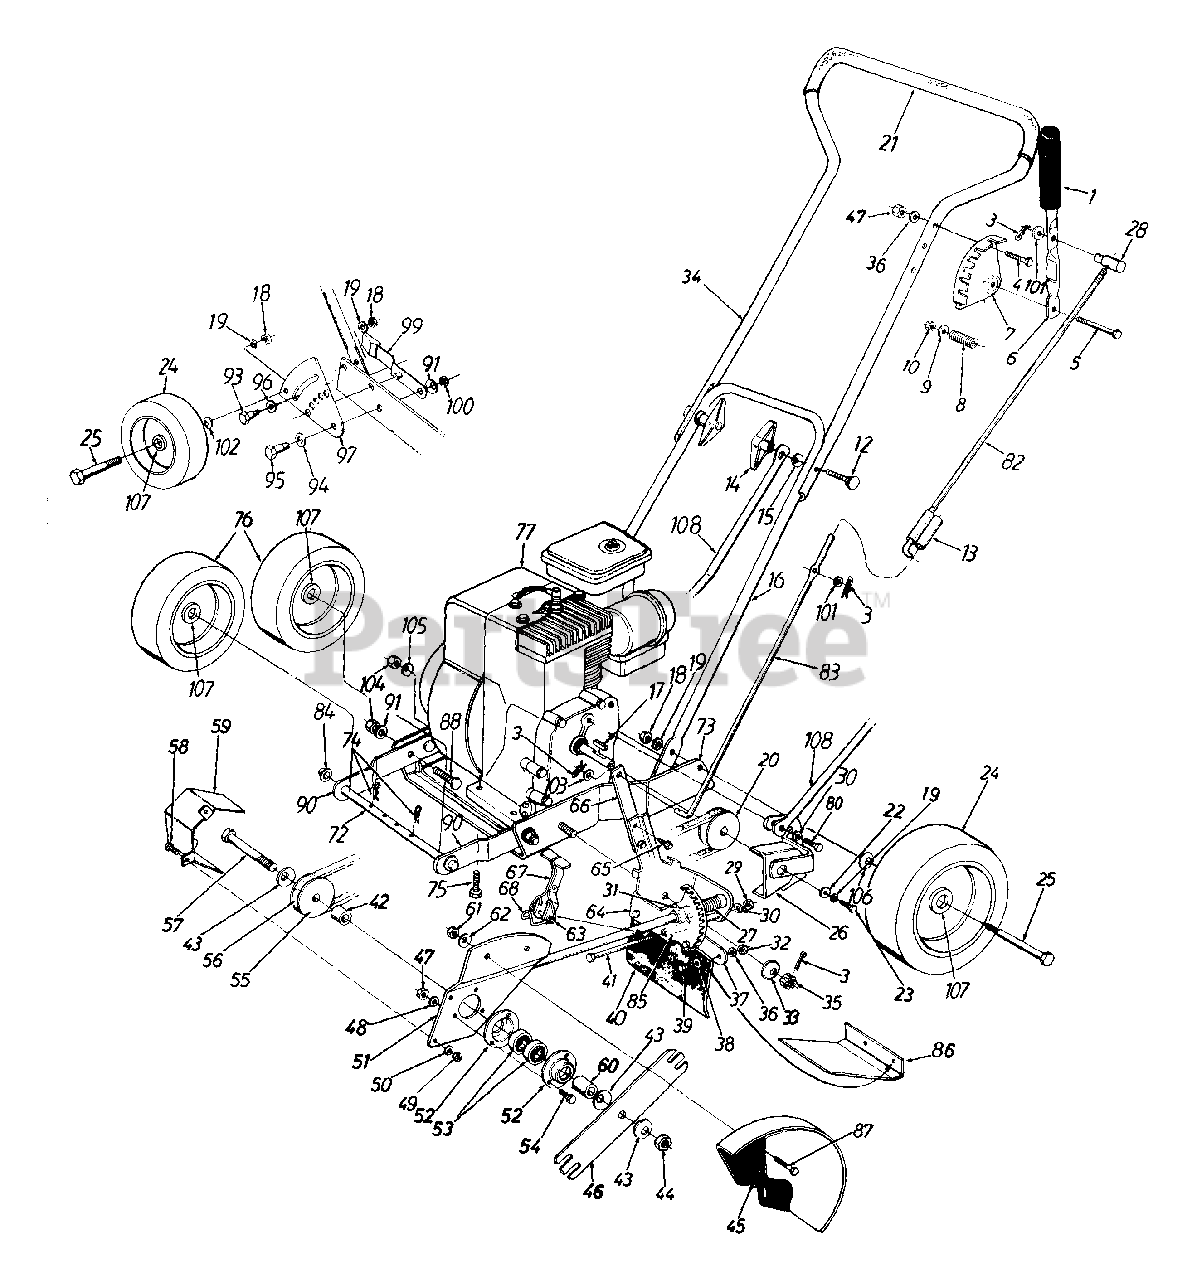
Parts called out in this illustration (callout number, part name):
1	Foam Grip
2	Hex L-Nut 1/4-20 Thd.
3	Cotter Pin 5/16" Dia.
4	Hex Bolt 1/4-20 x 1.25" Lg.
5	Hex Bolt 5/16-18 x 2" Lg.
6	Engagement Handle
8	Compression Spring 1.38" Lg.
9	Fl-Wash. .344" I.D.
10	Hex L-Nut 5/16-18 Thd.
12	Curv. Hd. Bolt 5/16-18 x 2" Lg.
13	Clutch Rod Lock
14	Wing Nut Ass'y.
15	Saddle Wash. .32" I.D. x .937"
16	Lower Handle
17	Sq. Key 3/16" x .75" Lg.
18	Hex Nut 3/8-16 Thd.
19	L-Wash. 3/8" I.D.
20	Engine Pulley
21	Foam Grip
22	Fl-Wash. .385" I.D.
23	Hex Bolt 3/8-24 x 1" Lg.
24	Rear Wheel Ass'y.
25	Shoulder Bolt .498" Dia.
28	Ferrule
29	Hex Nut 5/16-18 Thd.
30	L-Wash. 5/16" I.D.
31	Spring Pin Spir. 1/4" Dia.
32	Hex Nut 1/4-20 Thd.
33	Bell-Wash. .535" I.D.
34	Upper Loop Handle
35	Hex Slotted Nut 1/2-20 Thd.
36	L-Wash. 1/4" I.D.
37	Flap Bracket
38	Fl-Wash. .25" I.D.
39	Hex Bolt 1/4-20 x .62" Lg.
41	Hex Bolt 5/16-18 x 4.5" Lg.
42	Spacer 1.030" Lg.
43	Bell-Washer. .63" I.D.
44	Hex Jam L-Nut 5/8-18 Thd.
47	Hex Nut 1/4-20 Thd.
48	L-Wash. 1/4" I.D.
49	Hex Nut 1/4-20 Thd.
50	L-Wash. 1/4" I.D.
53	Ball Bearing .62" I.D.
54	Hex Bolt 1/4-20 x .62" Lg.
55	3/8" "V" - Pulley
56	V - Belt
57	Hex Bolt 5/8-18 x 4.5" Lg.
58	Hex Bolt 1/4-20 x .625" Lg.
59	Belt Guard
60	Sleeve .90" Lg.
61	Hex Nut 5/16-18 Thd.
62	Bell-Wash. .345" I.D.
63	Spring Pin Spir. 1/4" Dia.
66	Arm Extension
67	Adjustment Lever Ass'y.
68	Torsion Spring
69	Hex Nut 5/16-18 Thd.
70	L-Wash. 5/16" I.D.
72	Axle 8.20" Lg. (Front)
75	Hex TT-Tap Scr. 3/8-16 x 1" Lg.
76	Front Wheel Ass'y.
77	Engine
80	Hex Bolt 5/16-24 x .62" Lg.
82	Upper Clutch Rod
83	Lower Clutch Rod
84	Push Cap 1/2" Dia.
85	Spacer 3.765" Lg.
88	Ribbed Neck Bolt 3/8-24 x .8" Lg.
92	Fl-Wash. .39" I.D.
93	Shld. Bolt .5" Dia.
94	Bell-Wash. .515" I.D.
95	Shld. Bolt .50" Dia.
96	Fl-Wash. .51" I.D. x .94"
100	Hex Jam Nut 3/8-16 Thd.
101	Fl-Wash. .344" I.D. x .62" O.D.
102	Wave Wash. .51" I.D.
103	Fl-Wash. .406" I.D. x .81" O.D.
104	Hex Nut 3/8-24 Thd.
105	Bell-Wash. .396" I.D. x 1.14" O.D.
106	Wave Wash. .51" I.D.
107	Ball Bearing
108	Strut 15.91" Lg.
111	Fl-Wash. .25" I.D. x .62" O.D.
